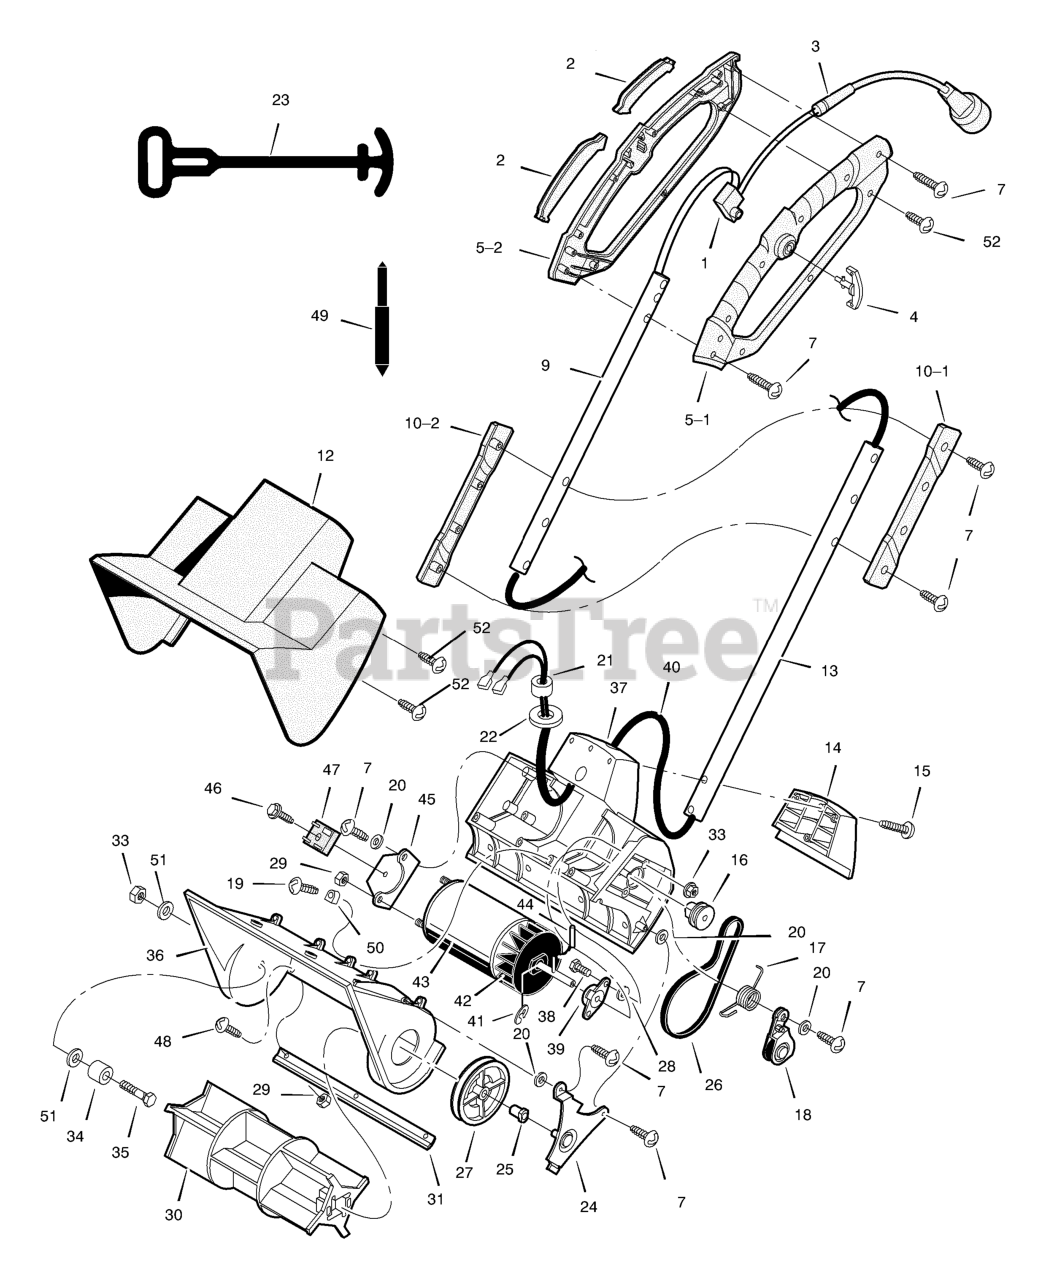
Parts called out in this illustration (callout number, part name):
1	Switch, Trigger
2	Trigger, Lever 12"
3	Lead, Connecting
4	Key -Double Notch
5	Set, Grip Trigger L&R 12"
5-1	Order Set
5-2	Order Set
7	Screw, #8 X 3/4 Poly
9	Tube -Handle, Upper
10	Set, Grip Center 12"
10-1	Order Set
10-2	Order Set
12	Housing, Upper 12"
13	Handle, Lower
14	Housing, Rear 12"
15	Screw, 10-9 X 1.062
16	Pulley, Engine
17	Spring, Torsion
18	Pulley, Idler & Brkt. Assy
19	Screw, #8 X1.00
20	#8 Washer
21	Clamp, Heyco
22	Washer, Flat .505 X 1.00X.06
23	Strain Relief, Cord
24	Bracket, Assy Drive Pulley
25	Bearing-Bronze
27	Pulley, Driven E12"
28	Washer, Plastic
29	Nut, #10-24 CNHKHX
30	Impeller, 12"
31	Blade, Scraper
33	Nut, 1/4-20 WDFLcenter Lock
34	Spacer, Impeller
35	Screw, 1/4-20X1.00
36	Housing, Impel 12"
37	Housing, Lower 12"
38	Screw, 1/4-20X.50
39	Bearing, Self Align
40	Wire Harness, E12"
41	Ring, Ret E
42	Fan, Motor, Extended
43	Motor, 120V
44	Pin, Grooved
45	Bracket, Motor Mount
46	Screw, #6-32X.75
47	Rectifier, Full Wave
48	Screw, 10-32X.50
49	Probe, Plastic
50	Plug, Retainer
51	Washer, 3/4X1/4X1/16
52	Screw, #8X.375 Poly Grip
